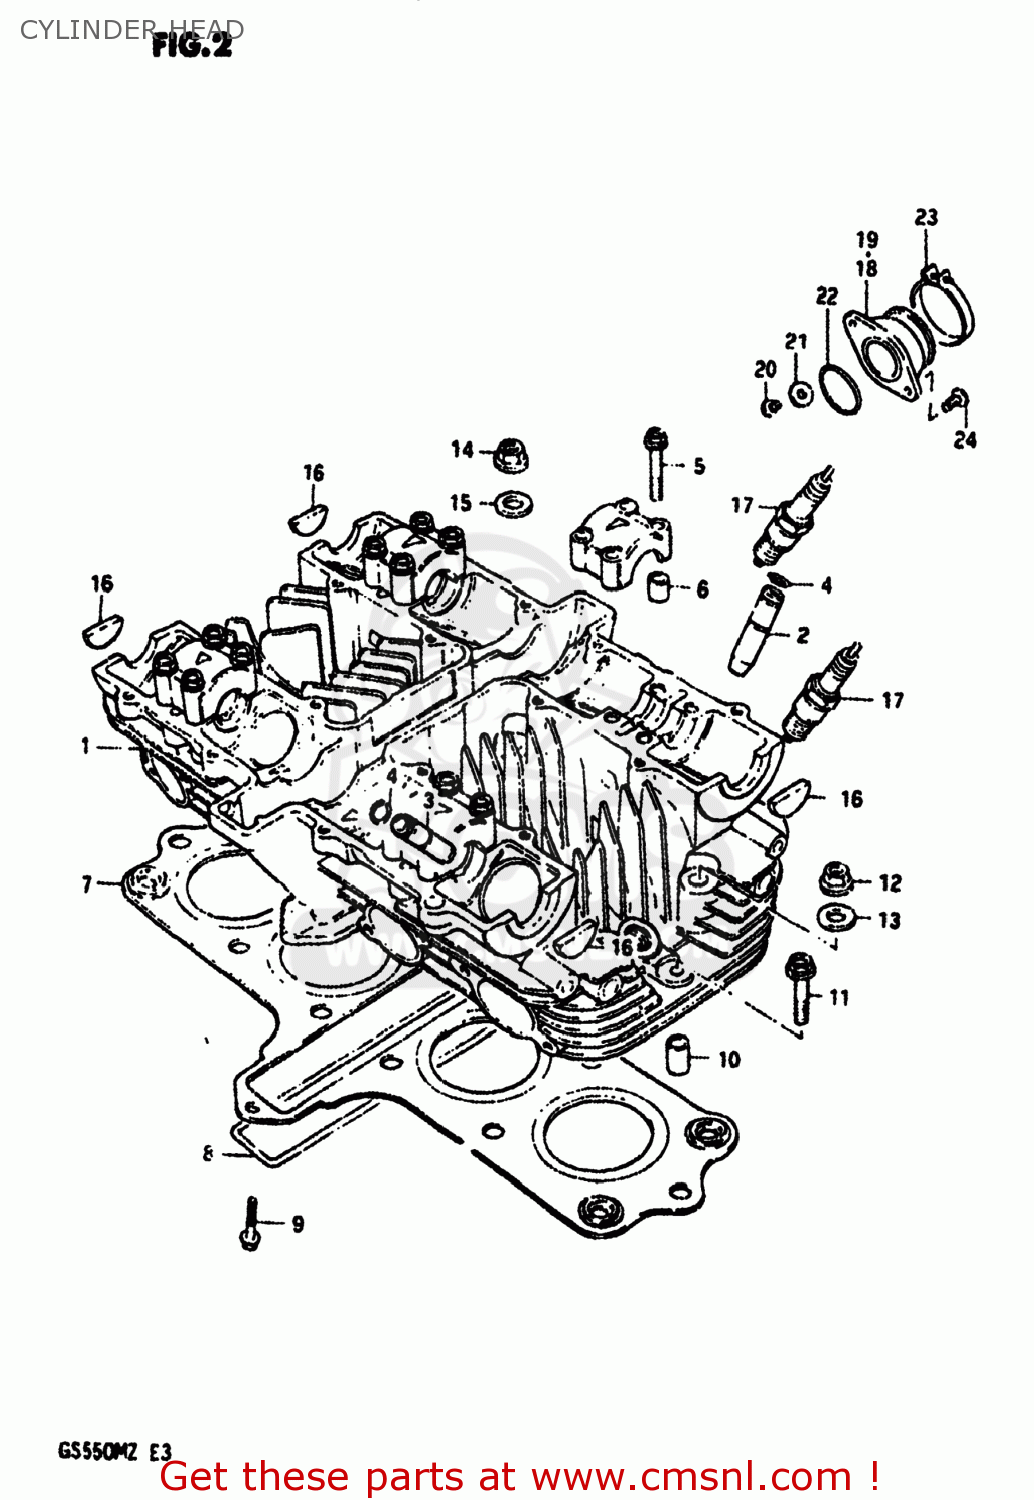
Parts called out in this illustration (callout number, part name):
1	HEAD SET,CYLINDER
2	GUIDE,INTAKE VALVE
3	GUIDE,EXHAUST VALVE
4	RING,SNAP
5	BOLT(6X39)
6	PIN(6.2X8X11)
7	GASKET,CYLINDER HEAD (MCA)
8	O RING(D:3,ID:26X157)
9	BOLT
10	PIN
11	BOLT,UNDER
12	NUT
13	GASKET(8.5X20X2.3) (NAS)
14	NUT
15	WASHER(8.5X19X2.3)
16	PLUG
17	SPARK PLUG
18	PIPE,INTAKE,R
19	PIPE,INTAKE,L
20	BOLT
21	WASHER
22	O-RING
23	CLAMP
24	SCREW
